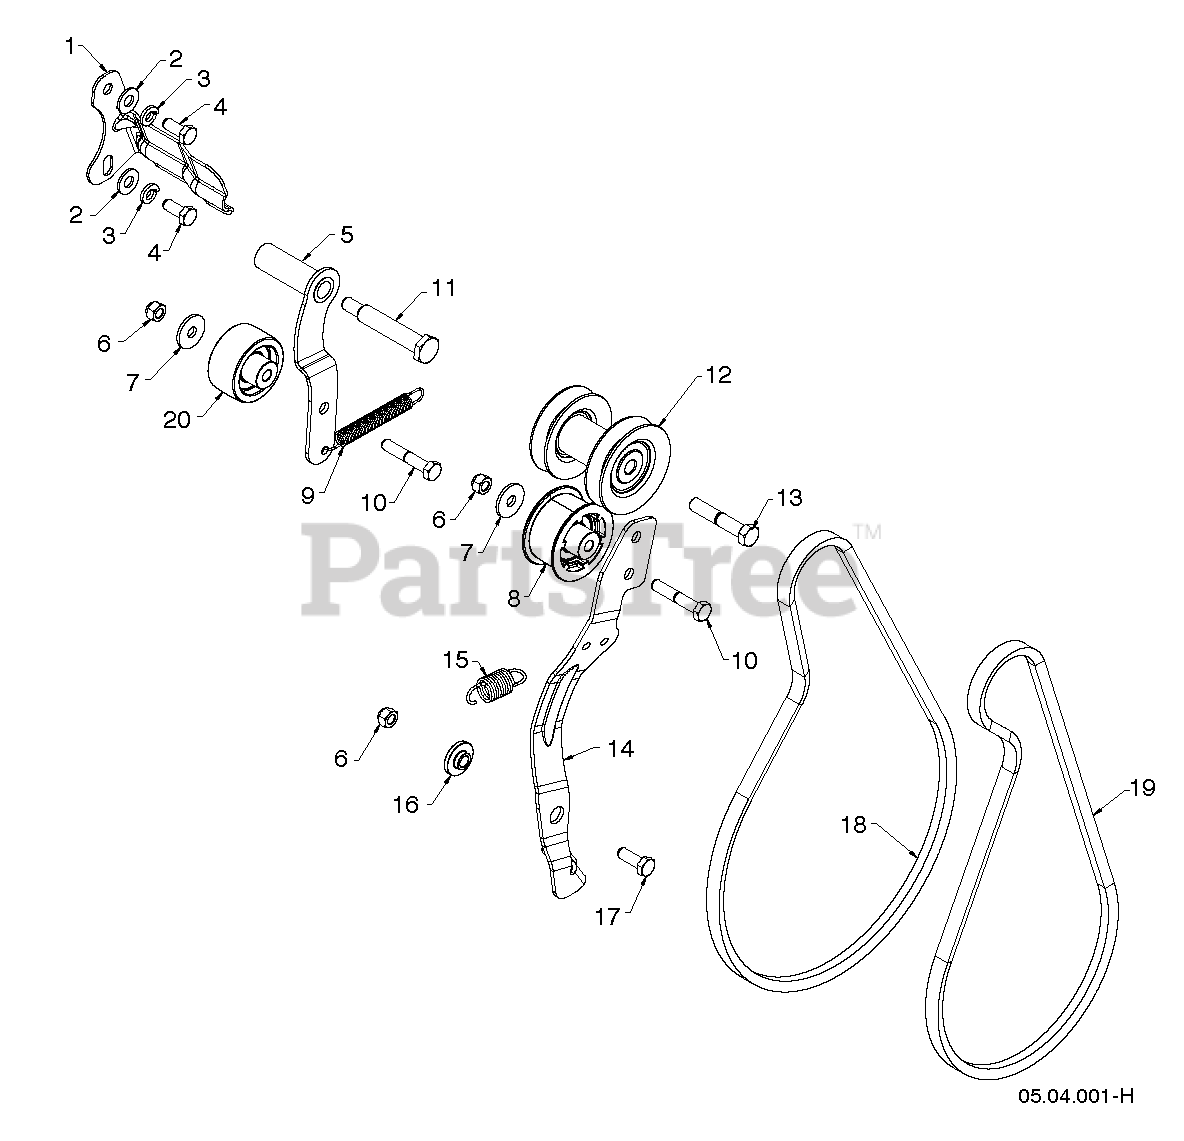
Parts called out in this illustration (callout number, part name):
1	BELT KEEPER BRACKET
2	WASHER M
3	LOCKWASHER
4	SCREW 5/16-24 X .75 GR5
5	ARM IDLER DRIVE WELDMENT_HOT
6	NUT.71038.31-18.HEX.NYLOCK
7	STEEL WASHER
8	PULLEY,IDLER,2.00 W SPA
9	SPRING RETURN IDLER ARM
10	BOLT, HEX 5/16-18X1-3/4
11	BOLT 5/16-24X2.25 HEX HEAD SHO
12	PULLEY.ASM.IMPELLER/DRIVE
13	BOLT.BLADE
14	BRACKET ARM.IDLER.IMPELLER ARM
15	SPRING RETURN, IDLER ARM, IMPE
16	BUSHING.BRAKE.ARM
17	BOLT
18	BELT.4L X 38.19
19	BELT IMPELLER_4L X 35.4
20	PULLEY.IDLER.FLANG.2.O/SPACER
